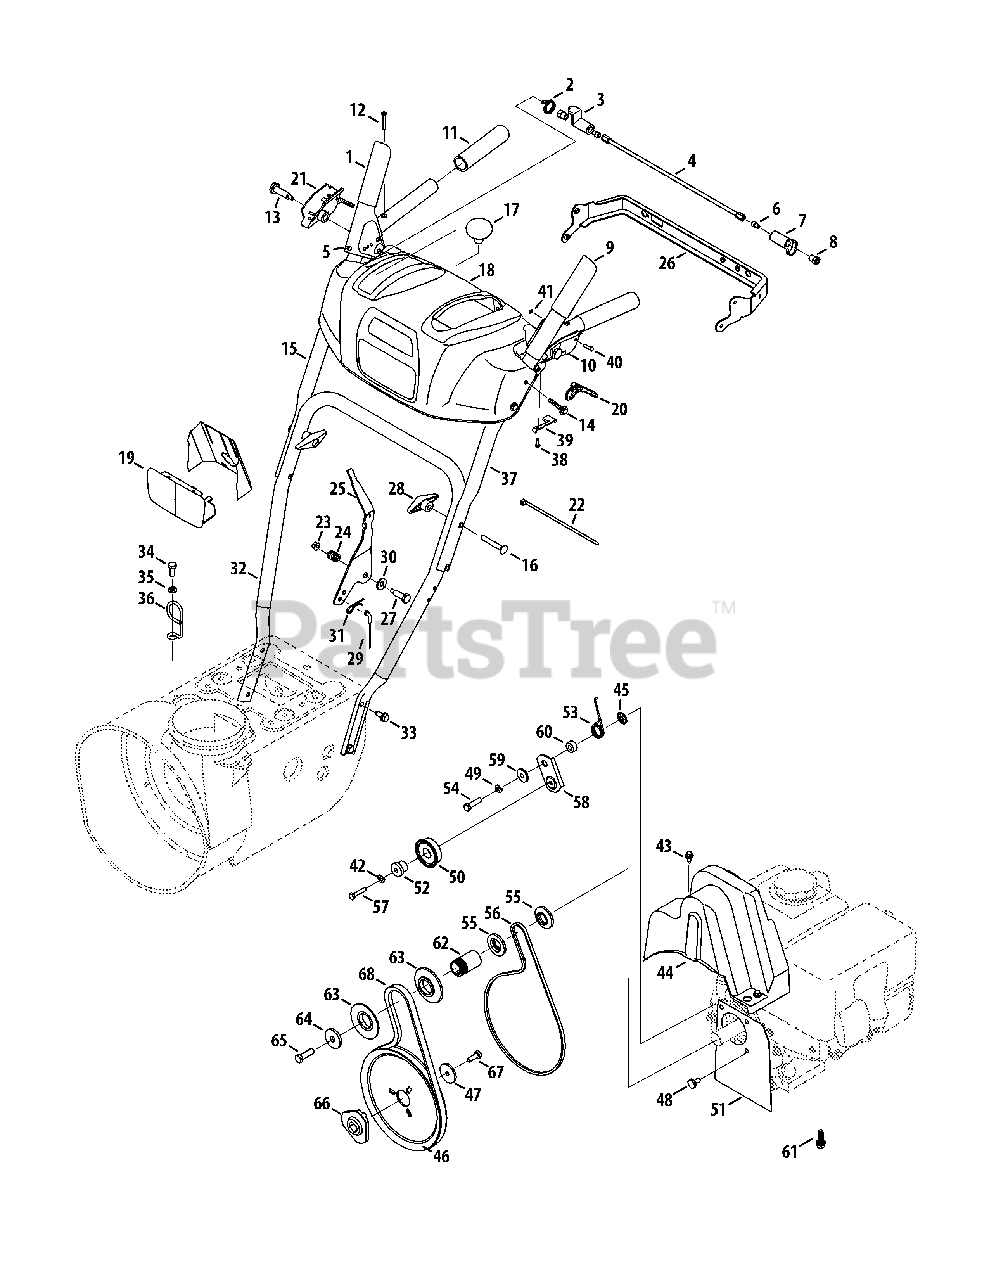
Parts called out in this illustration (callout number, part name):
1	Handle Engagement Ass’y RH
2	Torsion Spring
3	Lock Plate
4	Pivot Rod
5	Rubber Bumper
6	Screw, 1/4-20 x .500
7	Clutch Lock Cam
8	Shoulder Nut, 1/4-20
9	Handle Engagement Assembly LH
10	Handle Clutch Lock LH Assembly
11	Handle Grip
12	Screw, #10-24 x 0.375
13	Shoulder Screw, 1/4-20
14	Screw, 1/4-20 x 1.625
15	Upper Handle RH
16	Carriage Screw, 5/16-18 x 2.25
17	Shift Knob
18	Handle Panel
20	Steering Control
21	Handle Clutch Lock RH Assembly
22	Cable Tie
23	Flange Lock Nut, 1/4-20
24	Compression Spring
25	Shift Lever
26	Panel Bracket
27	Shoulder Screw
28	Wing Knob
29	Speed Selector Cable
30	Flat Washer
31	Click Pin
32	Lower Handle
33	Screw, 5/16-18 x 0.75
34	Screw, M8-1.25
35	Flat Washer, .330 x .630 x .0635
36	Cable Control Wire
37	Upper Handle LH
38	Screw, #8-16 x 0.50
39	Clutch Lock Spring
40	Pin, 3/16
41	Retainer Ring
42	Lock Washer
43	AB Screw, 1/4-20 x 0.625
44	Belt Cover
45	Push-on Nut
46	Auger Pulley
47	Flat Washer
48	Shoulder Screw
49	Lock Washer
50	Idler Pulley Assembly
51	Cover Plate
52	Spacer
53	Torsion Spring
54	Hex Screw, 5/16-24 x 1.25
55	Pulley Half
56	Belt, Wheel Drive
57	TT Screw, 1/4-20 x 1.25
58	Drive Clutch Idler Bracket
59	Shoulder Spacer
61	TT Sems Screw, 3/8-16 x 1.0
62	Spacer
63	Pulley Half
64	Flat Washer
65	Hex Bolt, 3/8-24 x 1.25
66	Pulley Adapter
67	Hex Bolt, 5/16-24 x 0.875
68	V-Belt,.500 x 35.00 Lg
